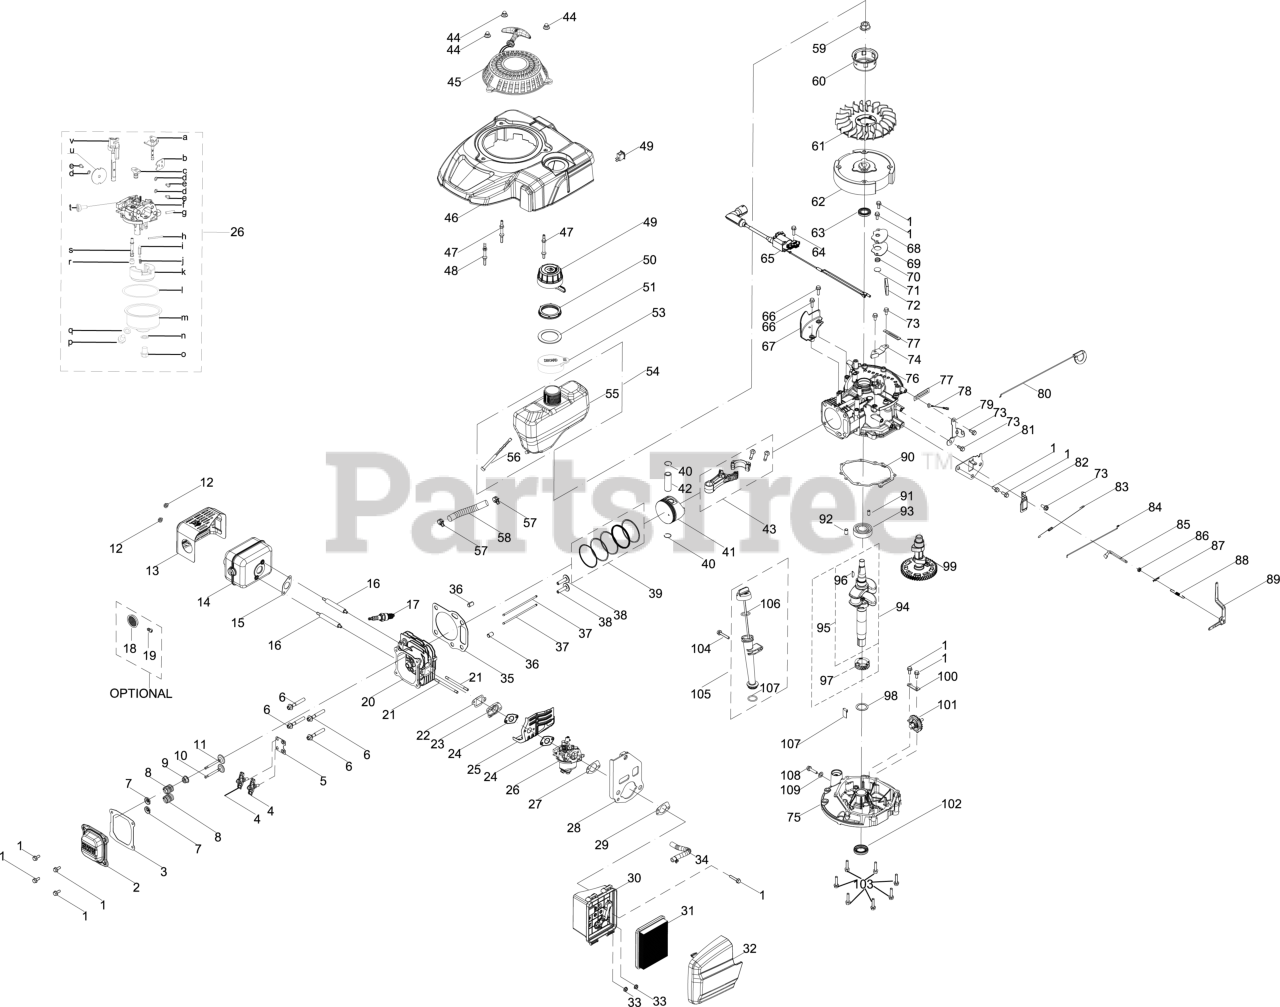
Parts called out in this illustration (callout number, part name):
1	BOLT M6-1 x 14 GR8.8
2	VALVE COVER
3	VALVE COVER GASKET
4	ROCKER ARM
5	PUSH ROD GUIDE
6	BOLT-M8 x 54
7	VALVE RETURN SPRING
8	VALVE SPRING
9	INTAKE VALVE SEAL
10	EXHAUST VALVE
11	INTAKE VALVE
12	HEX NUT
13	MUFFLER SHIELD
14	MUFFLER
15	MUFFLER GASKET
16	STUD M6-1 x 95
17	SPARK PLUG (F5RTC/RN11YC4/BPR5ES)
17	Cub Cadet SPARK PLUG-F5RTC
17	Genuine Factory Parts SPARK PLUG (14437)
18	SPARK ARRESTOR
19	SCREW M3.5 x 9.5
20	CYLINDER HEAD
21	STUD M6 x 90
22	CARBURETOR INSULATOR GASKET
23	CARBURETOR INSULATOR
24	CARBURETOR GASKET
25	CARBURETOR HEAT SHIELD
26	CARBURETOR ASSEMBLY HY-1X65LA
27	AIR FILTER BASE GASKET
28	AIR FILTER BRACKET
29	AIR FILTER BRACKET GASKET
30	AIR FILTER BASE
31	AIR FILTER
32	AIR FILTER COVER
33	HEX NUT
34	BREATHER HOSE ASSEMBLY
35	CYLINDER HEAD GASKET
36	PIN (10MMx16MM)
37	PUSH ROD
39	PISTON RING SET
40	WRIST PIN CLIP
41	PISTION
42	PISTON PIN
43	CONNECTING ROD ASSEMBLY
44	ACORN NUT M6-1
45	RECOIL STARTER ASSEMBLY
46	ENGINE SHROUD ASSEMBLY
47	STARTER/SHROUD REAR STUD
48	STARTER/SHROUD FRONT STUD
49	IGNITION SWITCH
49	FUEL CAP W/TETHER
50	FUEL TANK NUT
51	FUEL TANK GROMMET
53	FUEL TANK DUST CAP
55	FUEL TANK
56	FUEL FILTER
57	CARBURETOR HOSE CLAMP
58	FUEL HOSE
59	FLYWHEEL NUT M14-1.5
60	STARTER CUP
61	COOLING FAN
62	FLYWHEEL
63	UPPER CRANKSHAFT SEAL
64	BOLT M6-1 x 20 GR8.8
65	IGNITION COIL
66	BOLT M6-1 x 25 GR8.8
67	ENGINE BRAKE COVER PLATE
68	BREATHER COVER PLATE
69	BREATHER GASKET
70	BREATHER VALVE SPRING
71	BREATHER VALVE
72	BREATHER SCREEN
73	BOLT M6-1 x 12 GR8.8
74	AIR VANE COVER
75	CRANKCASE COVER
76	CRANKCASE
77	FLEXIBLE CLAMP
78	GROUND WIRE
79	CHOKE CONTROL BRACKET
80	CHOKE CONTROL
81	COMPONENT BRACKET
82	GOVERNOR SHIELD
83	THROTTLE LINKAGE SPRING
84	THROTTLE LINKAGE
85	GOVERNOR ARM SHAFT
86	OIL SEAL
87	COTTER PIN
88	GOVERNOR SPRING
89	GOVERNOR ARM ASSEMBLY
90	CRANKCASE COVER GASKET
91	DOWEL PIN 7 X 14
92	DOWEL PIN 9 X 14
93	BEARING
95	CRANKSHAFT
96	WOODRUFF KEY
98	THRUST WASHER
99	CAMSHAFT
100	GOVERNOR GEAR MOUNTING PLATE
101	GEAR GOVERNOR
102	LOWER CRANKSHAFT SEAL
103	BOLT-M6-1 x 28 GR8.8
104	BOLT M6-1 x 35 GR8.8
104	OIL DIPSTICK ASSEMBLY
107	OIL RETURN SEAL
108	OIL DRAIN PLUG
109	FLAT WASHER
